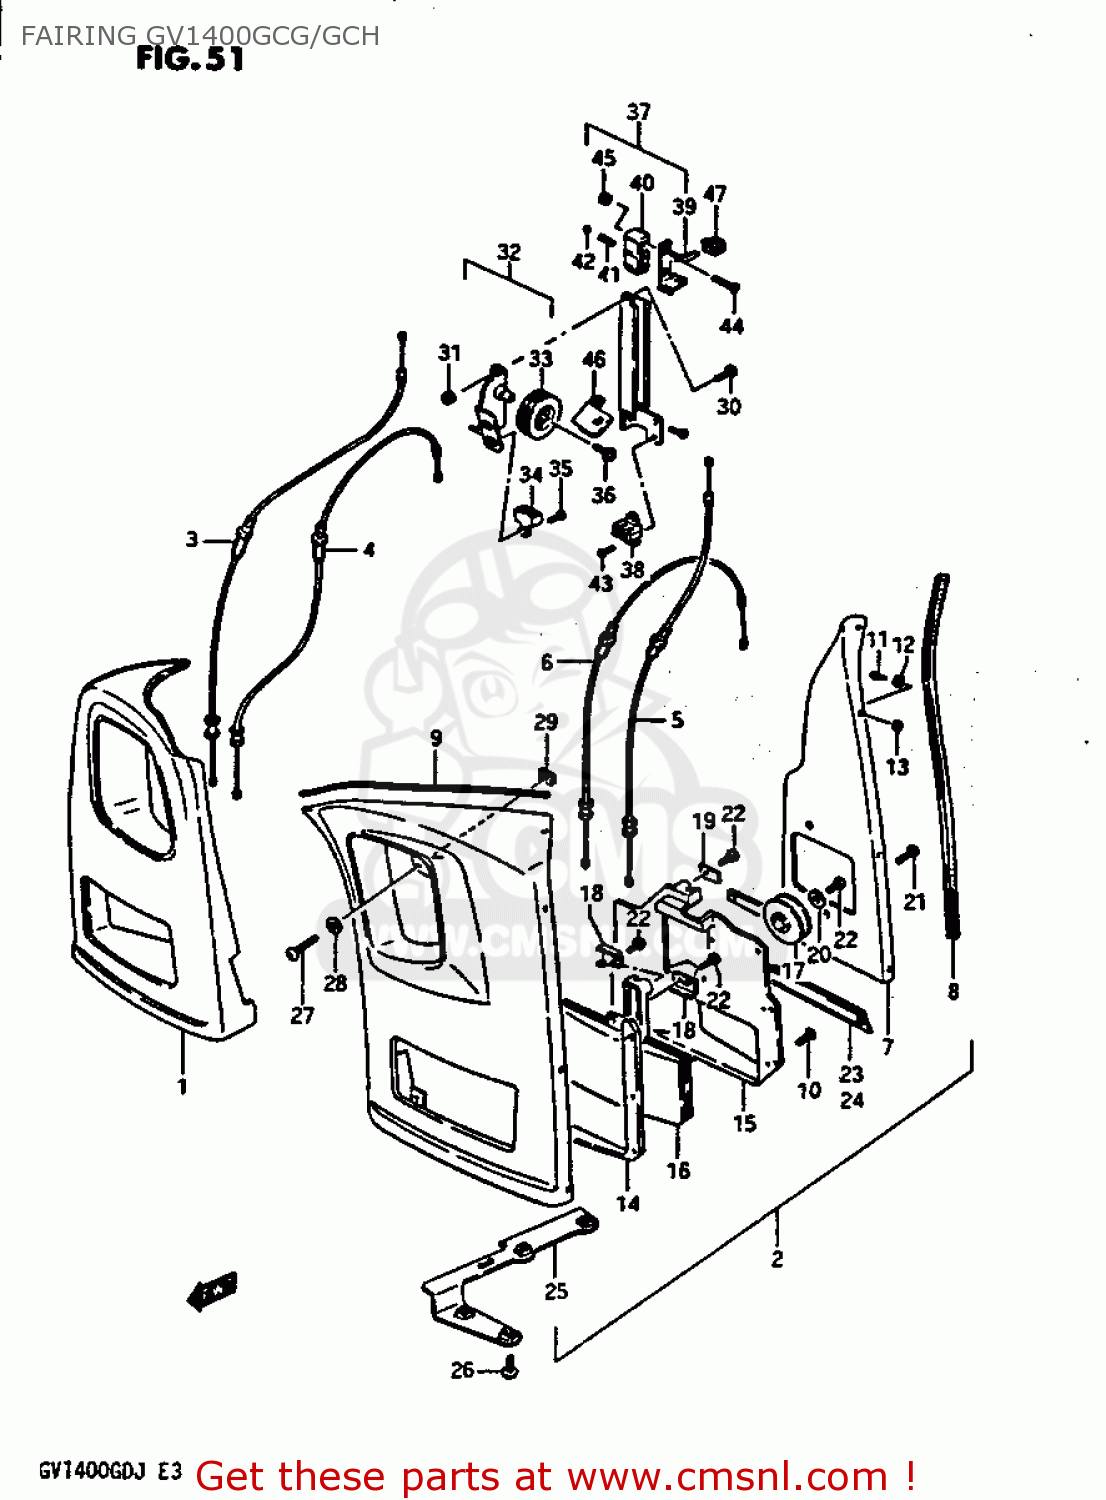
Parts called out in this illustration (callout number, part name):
1	FAIRING ASSEMBLY,EXTENSION
2	FAIRING ASSEMBLY,EXTENSION
3	CABLE COMP,VENTILATOR
4	CABLE COMP,VENTILATOR
5	CABLE COMP,VENTILATOR
6	CABLE COMP,VENTILATOR
7	EXTENTION, FAIRING REAR LH (BLACK)
8	MOLDING NO.1
9	MOLDING, NO.2
10	SCREW
11	SCREW
12	WASHER
13	NUT
14	GUIDE,VENT LID NO.1
15	GUIDE, VENT LID NO.2 RH
16	LID,VENTILATOR,RH (BLUE)
17	GUIDE,VENT CABLE
18	HOLDER, VENT CABLE RH
19	HOLDER, VENT CABLE CUTER
20	WASHER (4X16X1.2)
21	SCREW
22	SCREW
23	MOLDING, NO.3
24	MOLDING, NO.4
25	BRACKET, EXTENTION RH
26	SCREW, FRONT & REAR
27	SCREW
28	WASHER (5.5X14X1.2)
29	NUT
30	BOLT 6X16
31	NUT 6MM
32	GUIDE ASSEMBLY,VENTILATOR
33	GUIDE, VENT CABLE
34	GUIDE, VENT OUTER CABLE
35	SCREW, 4X10
36	SCREW, FRONT & REAR
37	OPERATION ASSEMBLY,VENTILATOR
38	GUIDE, VENT OUTER CABLE
39	LEVER, VENT OPERATION
40	SLIGER
41	SPRING
42	BALL
43	SCREW, 4X10
44	SCREW
45	NUT
46	BRACKET COMP,VENT OPERATING
47	KNOB,VENTILATOR OPERATING
